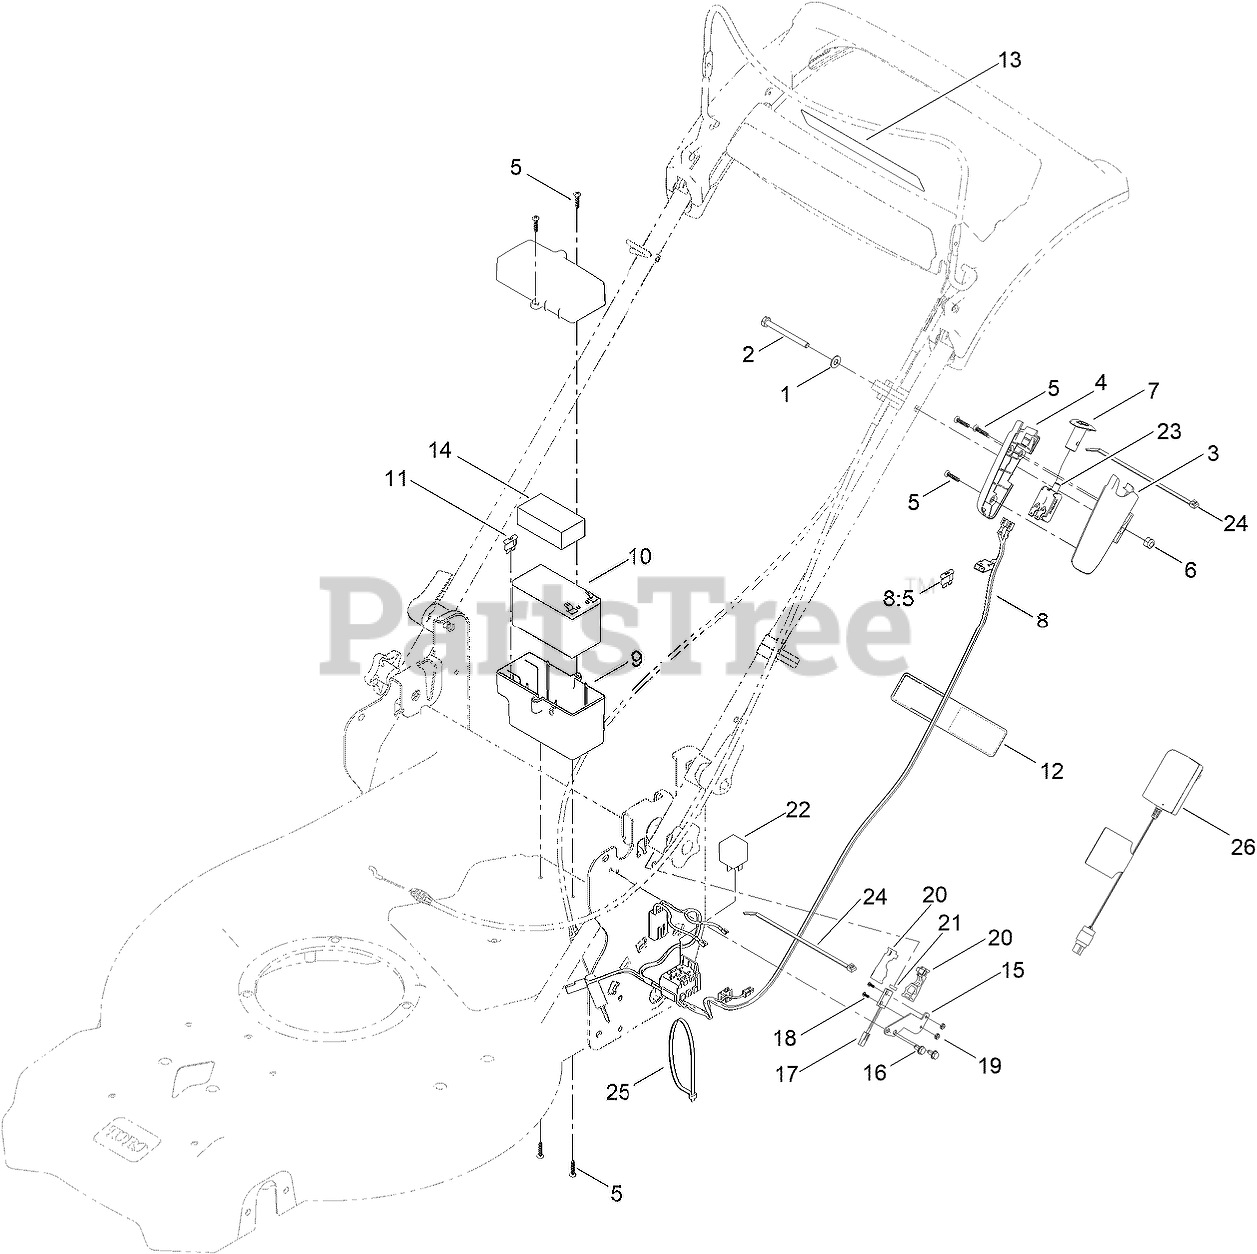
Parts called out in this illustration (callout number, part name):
1	WASHER-FLAT
2	SCREW-HH
3	HOUSING-SWITCH, LH
4	HOUSING-SWITCH, RH
5	SCREW-PPH
6	NUT-HEX
7	BUTTON-SWITCH
8	HARNESS-WIRE, SR5 VERT STOW
8:5	FUSE-40 AMP
9	BATTERY BOX ASM
10	BATTERY-NONSPILLABLE, 12 V
11	FUSE-40 AMP
12	DECAL-BATTERY CHARGING
13	DECAL-BUTTON, PUSH
14	FOAM-BATTERY, TOP
15	BRKT-SWITCH, SS
16	SCREW-HWH
17	REED SWITCH ASM
19	NUT-LOCK, NI
20	HOUSING-MAGNET
21	MAGNET
23	SWITCH-PUSH BUTTON
24	TIE-CABLE
25	TIE-CABLE
26	CHARGER, BATTERY (12V)
